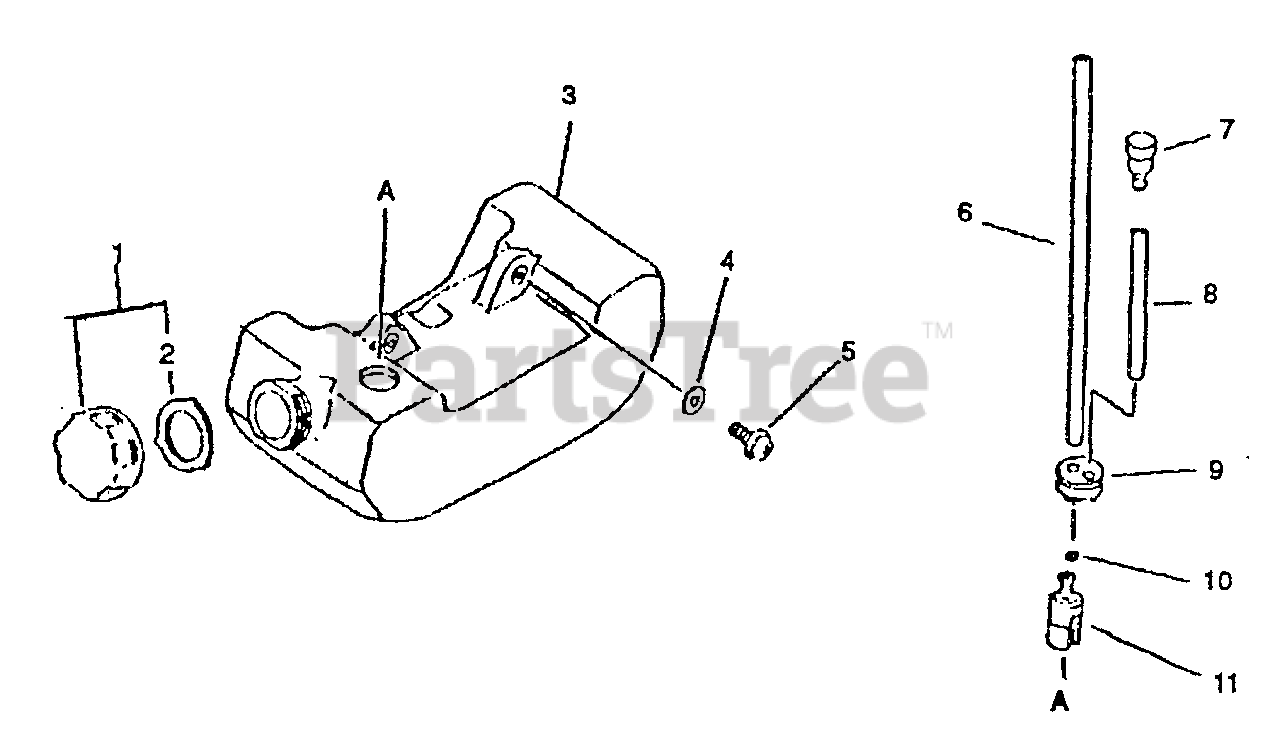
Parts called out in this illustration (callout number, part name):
1	CAP ASSY
2	GASKET, FUEL CAP
3	TANK, FUEL
4	WASHER 5.5×12×0.8
5	SCREW 5×16
6	PIPE, FUEL
7	VENT ASSY
8	PIPE K43B3×5×70
9	GROMMET, FUEL
10	CLIP 6 MM
11	FILTER, FUEL
